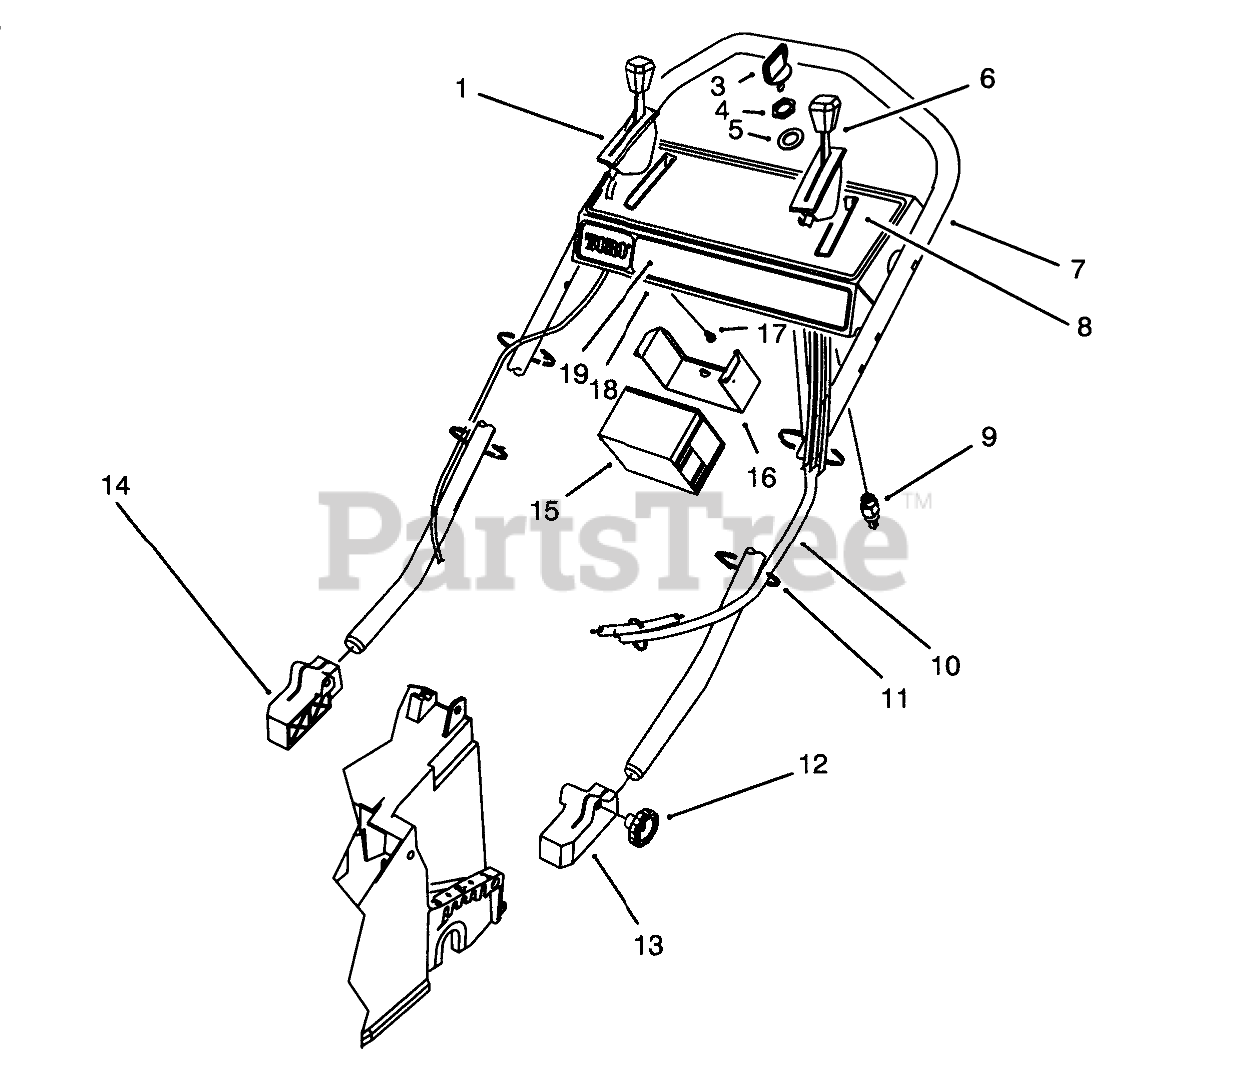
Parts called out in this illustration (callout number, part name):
1	GROUND SPEED CONTROL
3	KEY-IGNITION
4	NUT-HH
5	WASHER-TOOTH, INTERNAL
6	THROTTLE CONTROL
7	HANDLE PVC DIP
8	DECAL-INSTRUCTION KEY
9	Switch-Starter (Incl. Ref. #4 & 5)
10	Harness-Wire
11	TIE-CABLE
13	MOUNT-HANDLE, LH
14	MOUNT-HANDLE, RH
15	BATTERY ASSEMBLY
16	Retainer-Battery
17	SCREW-HWHTF
18	Panel-Control (Incl. Ref. #8 & 19)
19	DECAL - PANEL KEY
